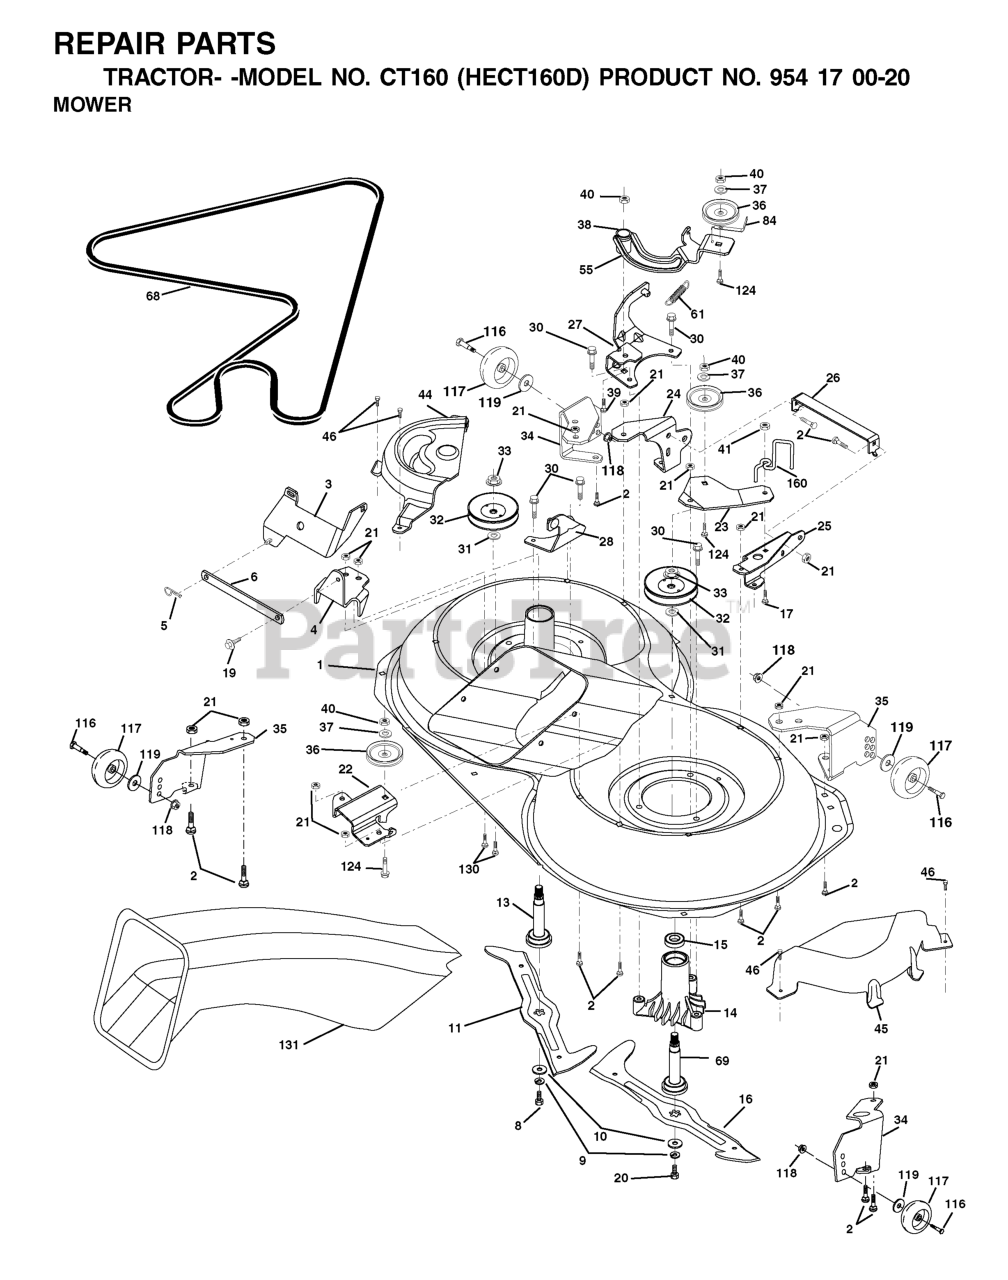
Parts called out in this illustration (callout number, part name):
1	Housing Asm. Mower 107 CRD
2	RP BOLT 5/16-18 X3/4 ZN/YEL GR
5	RETAINER-SPRNG RB
6	BAR.SWAY.92.CRD
8	BLADE BOLT
9	LOCKWASHER
10	WASHER.BLADE
11	BLADE, LH (CTH150)
13	SHAFT ASM VENT
14	HOUSING.MANDREL.VENTED (MACHD)
16	RP BLADE RH (CTH150)
19	BOLT SHD 5/16-18
21	LOCKNUT
22	BRACKET.IDLER.RR.107.CRD
25	BRACKET.SUSPENSION.RF.107.CRD
26	BRACE.SUPT.SUSP.FRT.CRD
28	BRACKET
30	SCREW THDROL ROLLING WASHER HD
31	WASHER
33	NUT
34	BRACKET
36	PULLEY.IDLER.4.25
37	WASHER
44	Cover Mandrel Lh 107 CRD
45	MANDREL COVER RH
46	SCREW.1/4-20X5/8
55	ARM.IDLER.107.CRD
68	HEX-BELT 107 MOWER
69	SHAFT.ASM.W/LWR.BRG.RH.THREAD
84	KEEPER, BELT IDLER
116	BOLT, SHOULDER
117	WHEEL GAGE DONUT
118	LOCKNUT
119	WASHER.5/16.FLAT.STE.STD.
124	BOLT.3/8-16X1.50
130	BOLT.CARR.SQNK.5/16-18UNC.X3/4
131	CHUTE BAGGER
